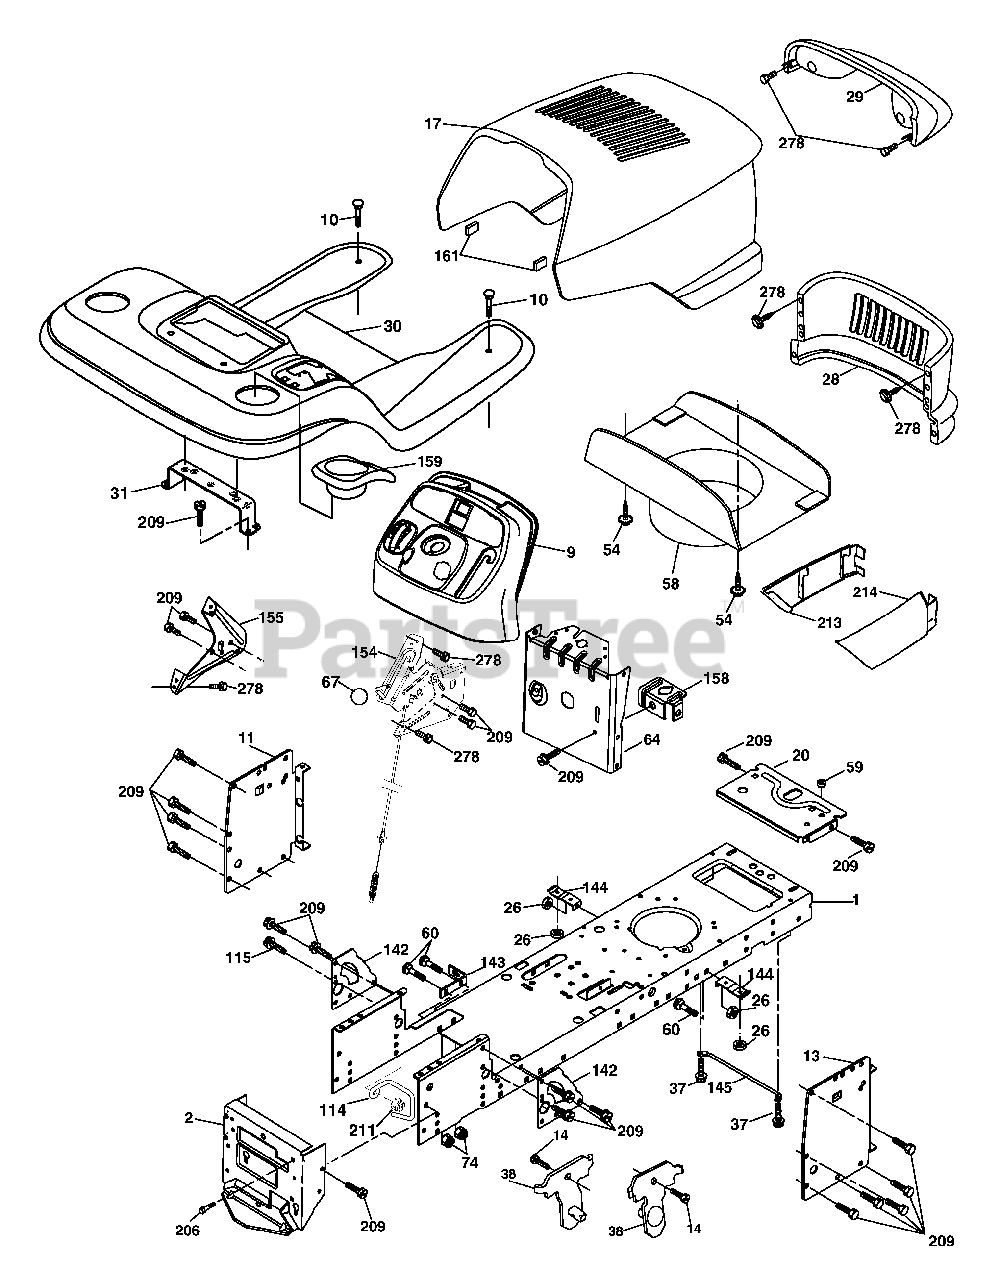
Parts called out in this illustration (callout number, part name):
1	Chassis
2	Drawbar
10	Bolt Carriage 3/8-16 x 1
11	Panel Dash Lh
13	Panel Dash Rh
14	Screw Thdrol 3/8-16 x 1/2
17	Hood
26	Nut Lock Hex W/Ins 3/8-16 unc
28	Grille
29	Lens Bar
31	Bracket Fender
37	Screw Thdrol 6/16-18 x 1/2 TYT
38	Bracket Asm Pivot Mower Rear
54	Screw WSHD Hex 10-32 x 5/8
58	Duct Air
59	Bushing 1.375 OD
60	Bolt RDHD SQNK 3/8-16 UNC x 3/4
64	Dash Lower STLT
67	Knob
74	Nut Crownlock 3/8-16 UNC
114	Keeper Belt Rear LH
115	Screw THDROL 3/8-16 x 1-1/4
142	Plate Reinforcement STLT
143	Bracket Swaybar Chassis
144	Bracket Footrest Step-Thru
145	Rod Pivot Chassis/Hood
154	Clutch Asm Manual Brkt.
155	Bracket Dash LH
158	Bracket Parking Brake
159	Cupholder
161	Bumper Hood
206	Bolt Shoulder 5/16-18
209	Screw Hexwsh Thdr 3/8-16 x 3/4
211	Nut Hex Flange Lock
213	Skirt Grille RH
214	Skirt Grille LH
258	Lens Grille Pro RH
259	Lens Grille Pro LH
263	Bezel Grille RH
264	Bezel Grille LH
278	Screw 10 x 3/4 Single Lead-Hex
